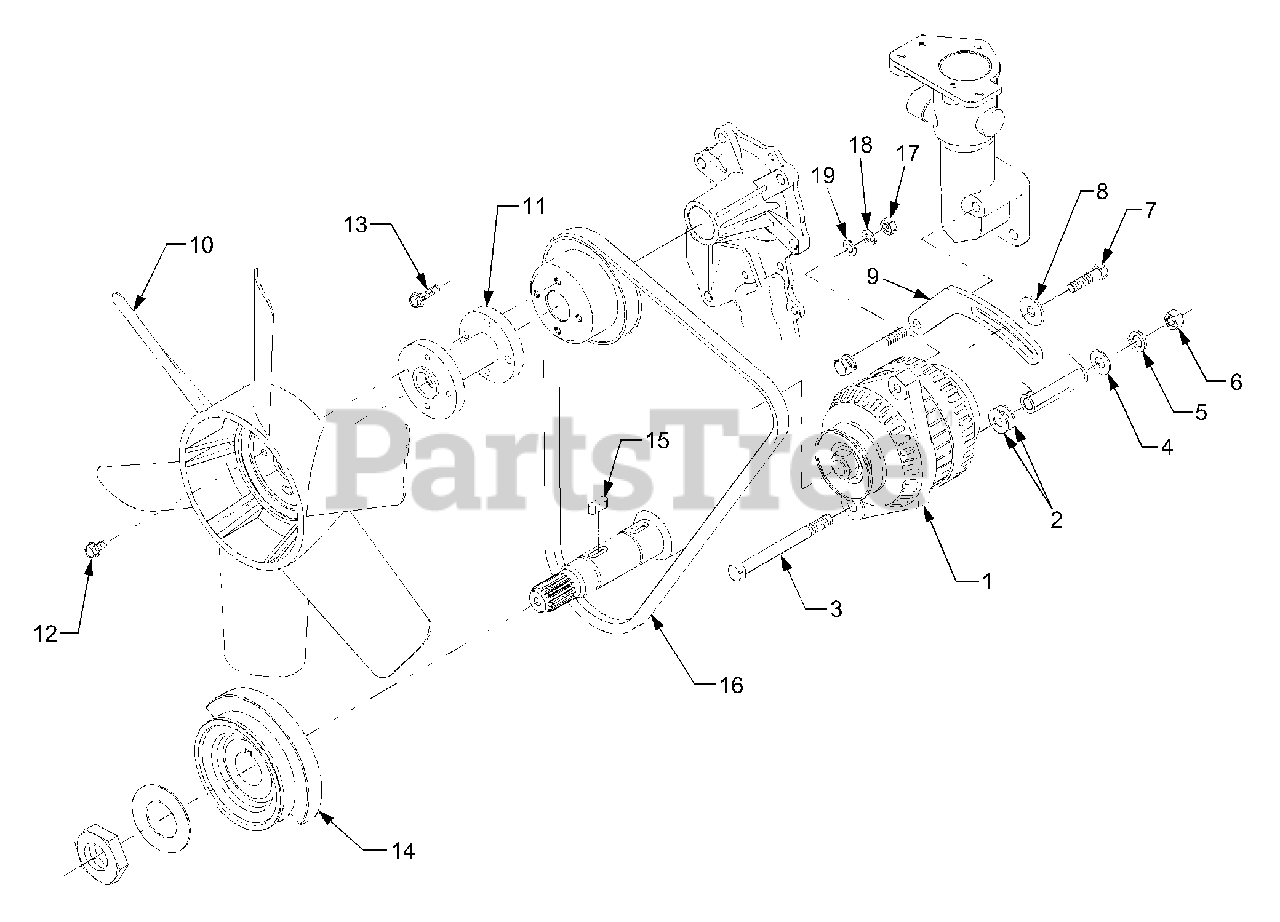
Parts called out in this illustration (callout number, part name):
4	Washer, Plain
5	Washer, Spring
8	Washer, Plain
10	Fan, Coolling
14	Pulley, Fan Drive
18	Washer, Plain
19	Washer, Spring
